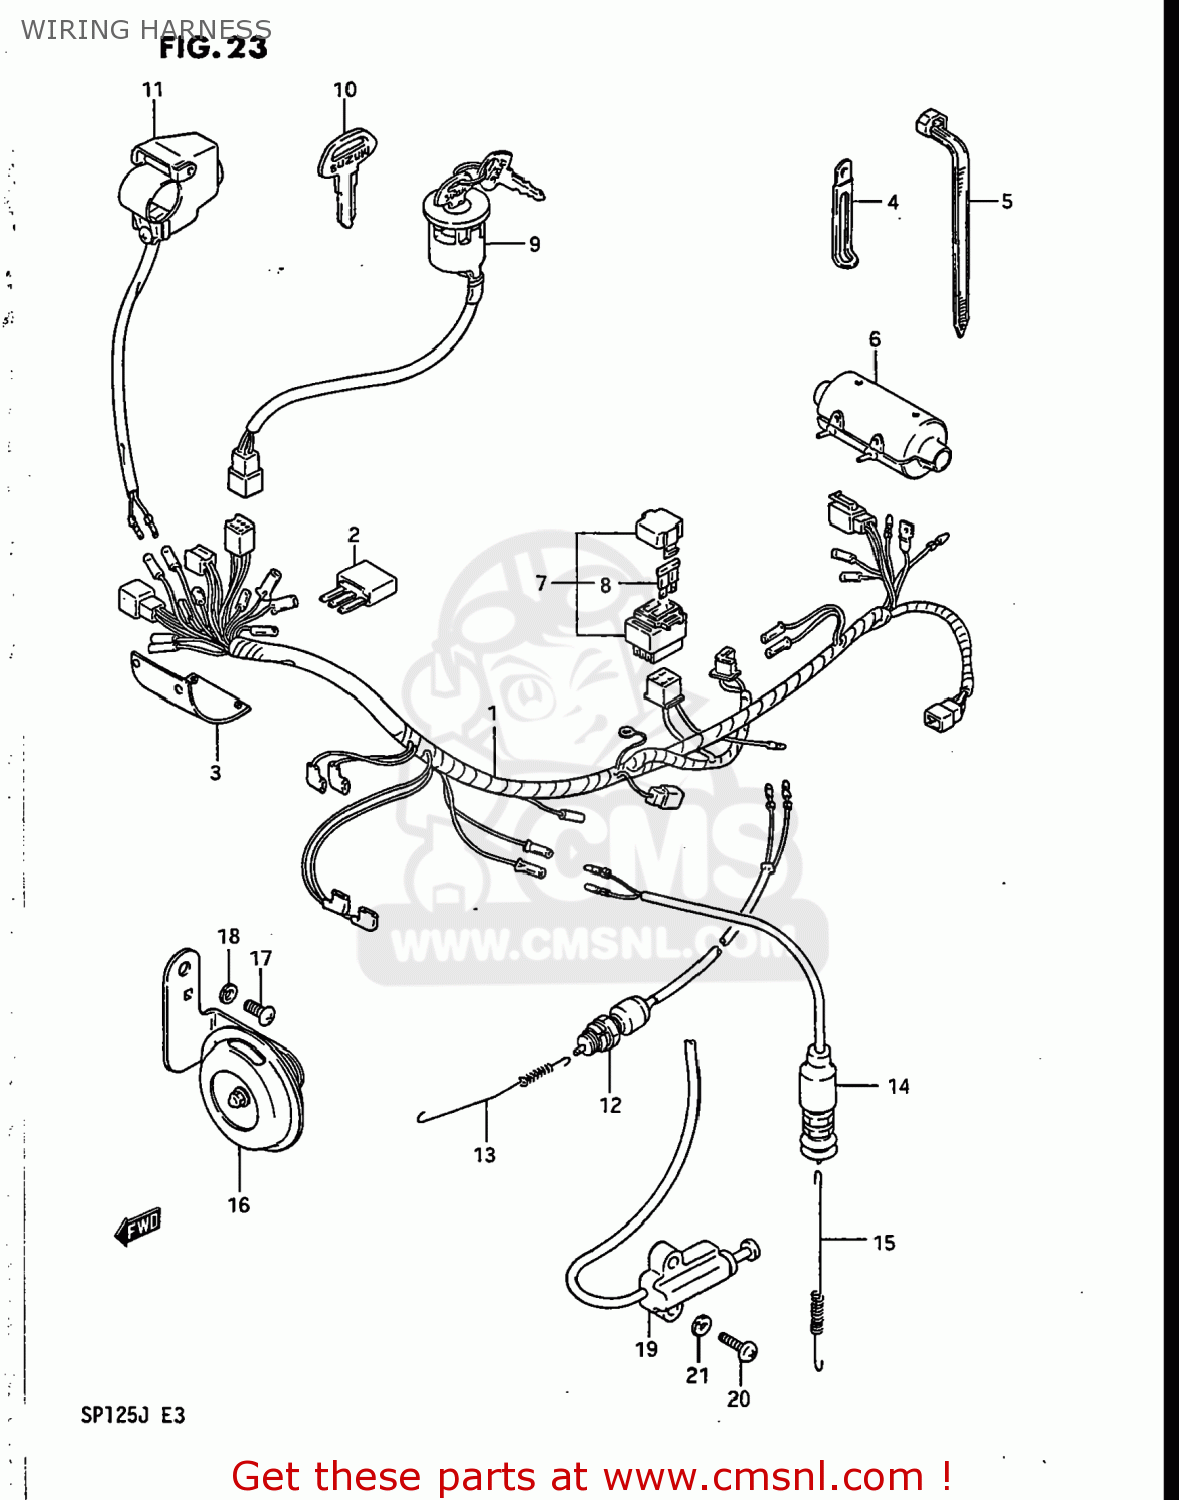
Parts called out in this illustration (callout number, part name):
1	HARNESS,WIRING
2	DIODE(STANLEY DE8804)
3	BOOT,WIRING HARNESS
4	CLAMP
5	CLAMP(L:125)
6	BOOT,WIRING HARNESS
7	BOX ASSY,FUSE
8	FUSE(15A)
9	SWITCH ASSEMBLY,IGNITION
10	KEY,BLANK
11	SWITCH ASSY,ENGINE STOP
12	SWITCH ASSY,STOP LAMP
13	SPRING
14	SWITCH ASSEMBLY,SIDE STAND
15	SPRING
16	HORN ASSEMBLY
17	SCREW
18	WASHER,LOCK
19	SWITCH ASSEMBLY,SIDE STAND
20	SCREW
21	WASHER
